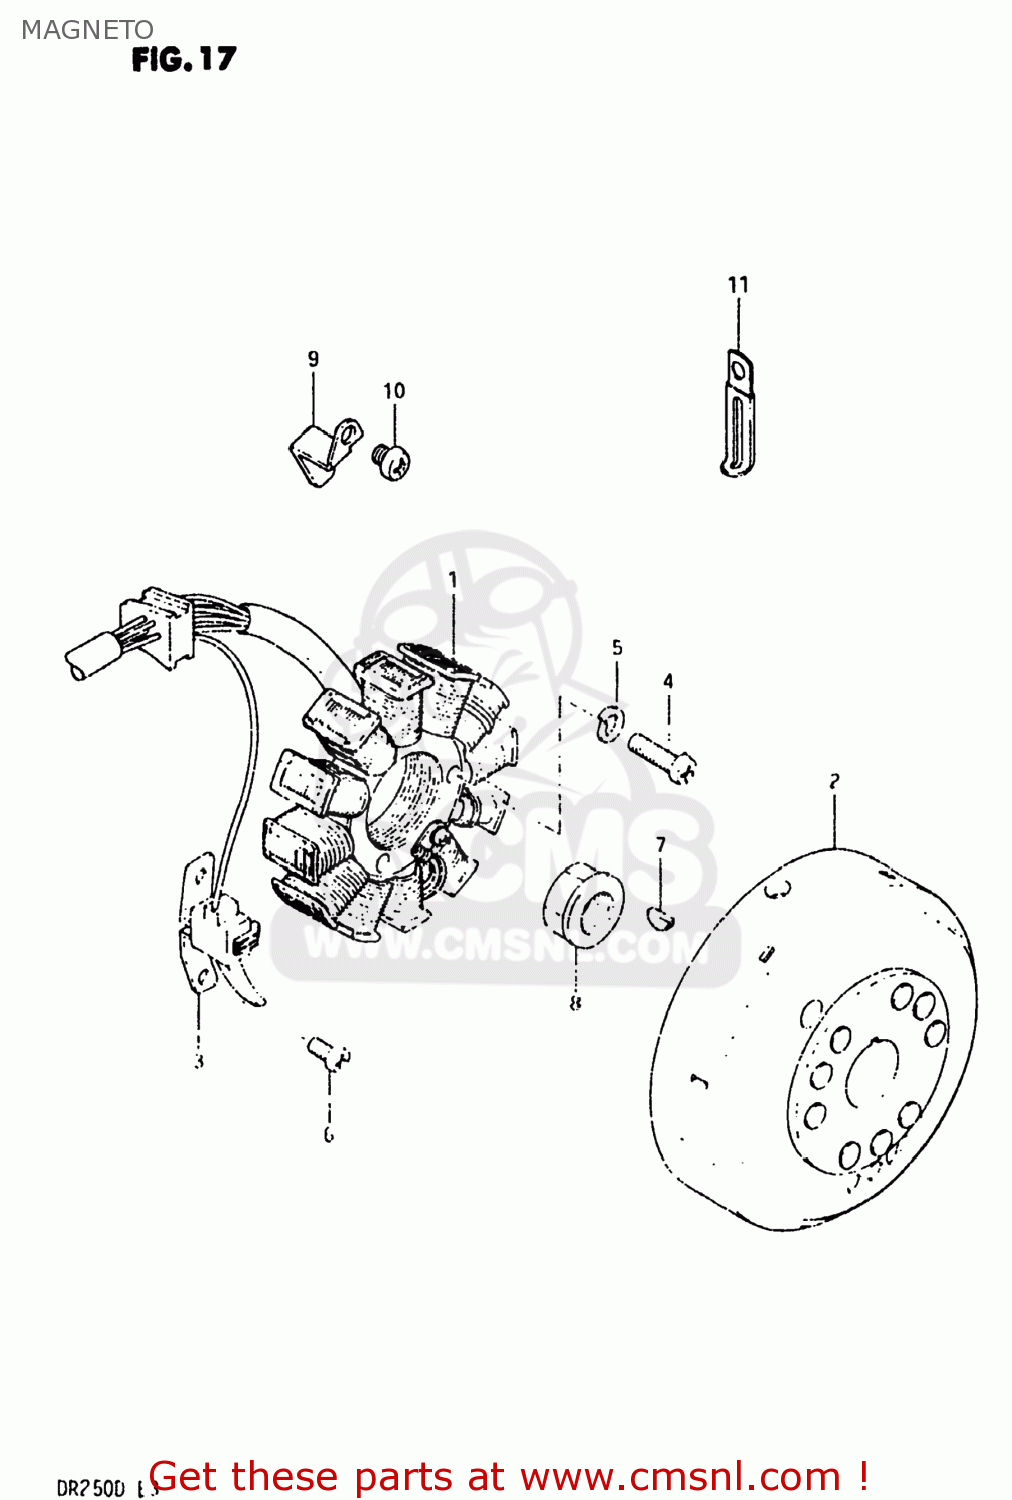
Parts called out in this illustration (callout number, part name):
1	STARTER ASSY
2	ROTOR,FLYWHEEL
3	COIL,PICK UP
4	SCREW
5	LOCK WASHER
6	SCREW
7	KEY 4MM
8	NUT,GENERATOR ROTOR
9	CLAMP,MAGNETO LEAD WIRE
10	SCREW
11	CLAMP L:35
